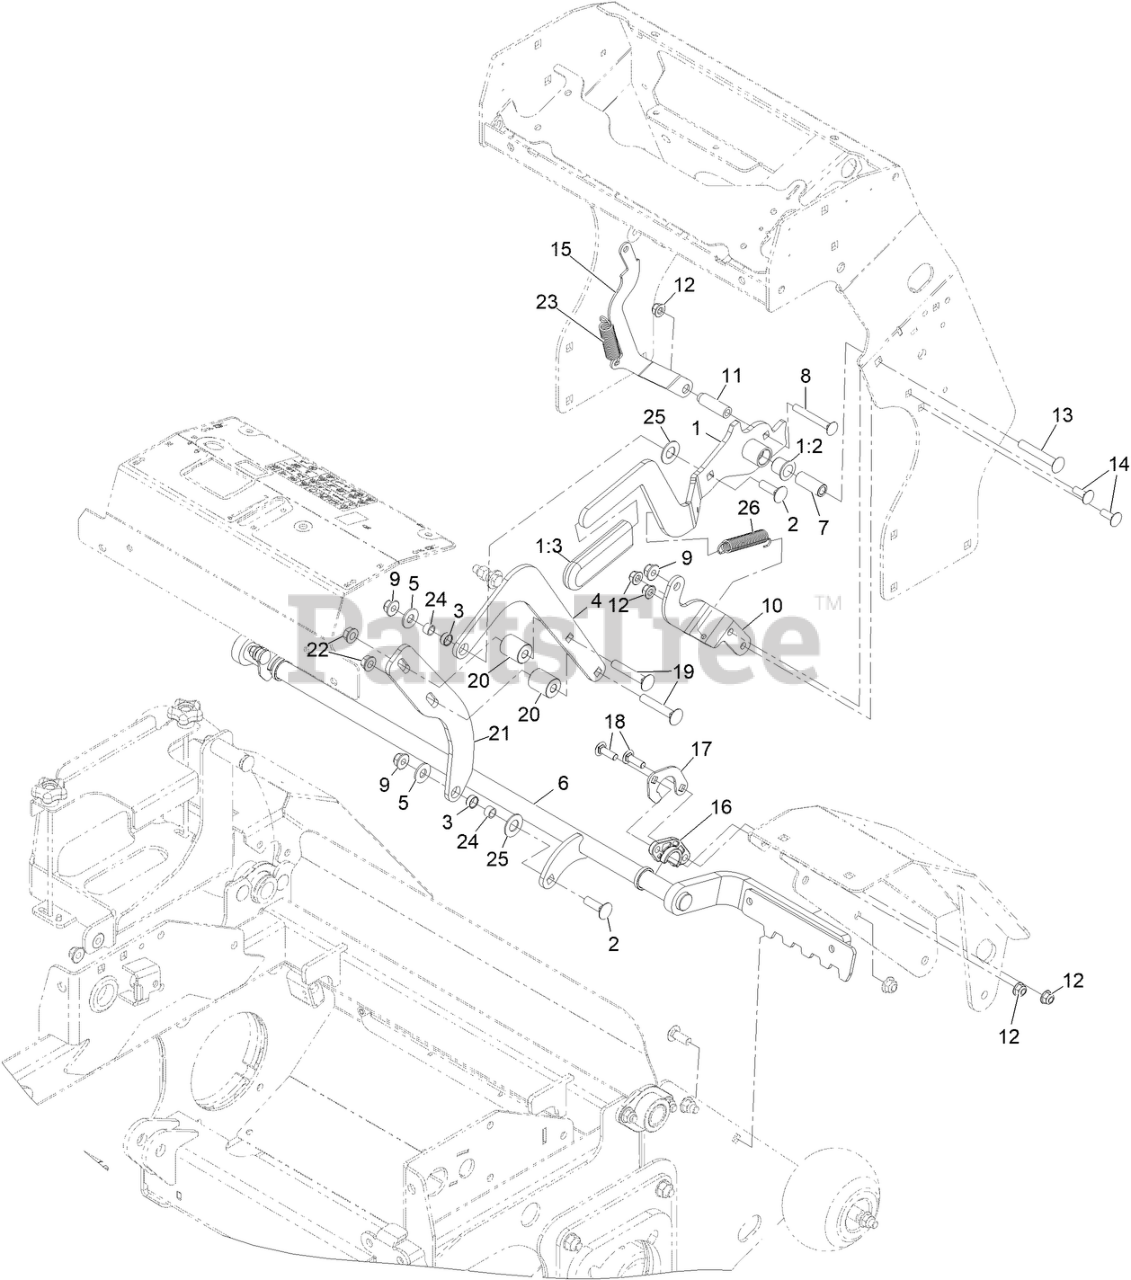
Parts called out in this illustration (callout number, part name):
1	ASM-HANDLE BRAKE
1:2	BUSHING-FLANGE
1:3	GRIP-LEVER
2	BOLT-CARR
3	BEARING-SLEEVE
4	LINK-BRAKE UPPER
5	WASHER-FLAT
6	ASM-BRAKE SHAFT
7	SPACER-PIVOT
8	SCREW-CARR
9	NUT-HF, NI
10	BRACKET-BRAKE LEVER SUPT
11	SPACER-.31 X 1.25 YZ
12	NUT-HF, NI
13	SCREW-CARR
14	BOLT-CARR
15	Link-Brake Control Lock
16	BEARING-FLANGE
17	SUPPORT, BEARING
18	SCREW-CARR
19	Bolt-Carriage 3/8-16 X 2 1/4
20	SPACER-.39 IDX1.0 ODX1.2 L
21	LINK - LOWER BRAKE
22	NUT-HHF, WHIZ
23	SPRING-EXTENSION
24	SPACER-BRAKE PIVOT
25	WASHER-PLASTIC
26	SPRING-EXTENSION
